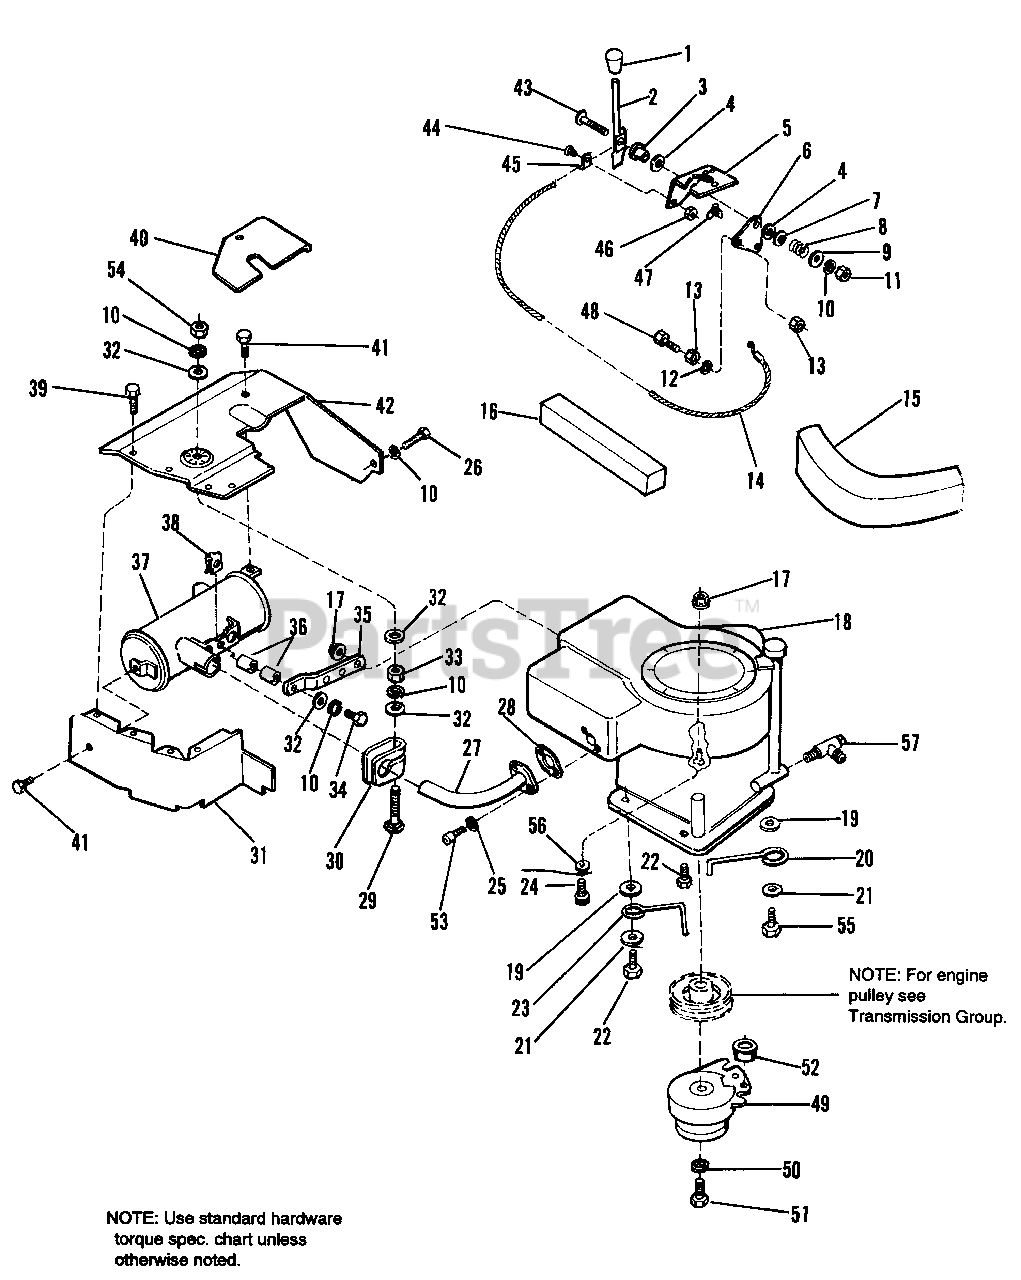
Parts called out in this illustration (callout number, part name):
1	KNOB, Small
2	HANDLE, Throttle
4	WASHER, Nylon
5	BRACKET, Throttle Mounting
6	PLATE, Spring
9	WASHER, Plain, 5/16
10	LOCKWASHER, 5/16
11	NUT, Hex, 5/1 6-18
12	LOCKWASHER, 1/4 (Qty.1 on 12.5 H.P.)
13	NUT, Hex, 1/4-20
14	CABLE, Throttle
15	SEAL, Air Inlet, 12.5 H.P.
15	SEAL, Air Inlet, 8.5 H.P.
16	SEAL, Air Duct, 8.5 H.P.
17	NUT, Hex, Flange, Whizlock, 5/16-18
18	ENGINE, 12.5 H.P. (Briggs & Stratton)
18	ENGINE, 12.5 H.P. (Briggs & Stratton) ENGINE, 8.5 H.P. (Briggs & Stratton)
19	WASHER, Plain
20	BELT STOP (Qty. 2 on Hydro)
21	WASHER, Plain, 3/8
22	SCREW, Taptite, 3/8-16 x 1-1/2
23	BELT STOP (Gear model only, Hydro model use Ref. No. 20)
24	SCREW, Hex, Flange, Whizlock, 5/16-18 x 1-1/2
25	LOCKWASHER, 5/16, 12.5 H.P.
25	LOCKWASHER, 1/4, 8.5 H.P.
26	CAPSCREW, Hex Hd., 5/16-18 x 3/4
27	PIPE, Exhaust, 12.5 H.P.
27	PIPE, Exhaust, 8.5 H.P.
28	GASKET, Muffler, 12.5 H.P.
28	GASKET, Muffler, 8.5 H.P.
29	CARRIAGE BOLT, 5/16-3 x 1-1/4
30	CLAMP, Muffler
31	DUCT, Top, L.H.
32	WASHER, 11/32
33	NUT, Hex, 5/16-18
34	CAPSCREW, Hex Hd., 5/16-18 x 1, 12.5 HP
34	CAPSCREW, Hex Head 5/16-18 x 2 G5
35	SUPPORT, Muffler
36	SPACER, 8.5 H.P. only
37	MUFFLER ASSY.
38	NUT, Speed, 5/16-18
39	SCREW, Hex Hd.,10-16 x 3/8
40	DUCT, Top, Muffler, 8.5 HP
41	SCREW, Hex, Flange, Taptite, 5/16-18 x 1/2
42	DUCT, Top, R.H.
43	CARRIAGE BOLT, 5/16-18 x 1-3/4
44	SCREW, Trusshead,10-32 x 1/2
45	CLIP, Bowden Wire
46	NUT ASSY.,10-32
47	SCREW, Plastite,1/4-20 x 5/8
48	CAPSCREW, Hex Hd.,1/4-20 x 1-1/4
49	ELECTRIC CLUTCH
50	LOCKWASHER, 7/16
51	CAPSCREW, Hex Hd., 7/16-20 x 2-1/2
52	SLEEVE, Clutch Anchor
53	CAPSCREW, Soc. Hd., 5/16-18 x 3/4, 12.5 HP
53	CAPSCREW, Soc. Hd., 1/4-20 x 3/4, 8.5 HP
54	NUT, Hex, Lock, Esna Light, 5/16-18
55	SCREW, Hex, Washer Hd., Taptite, 3/8-16 x 2
56	PUSHNUT
57	DRAIN VALVE, Oil
